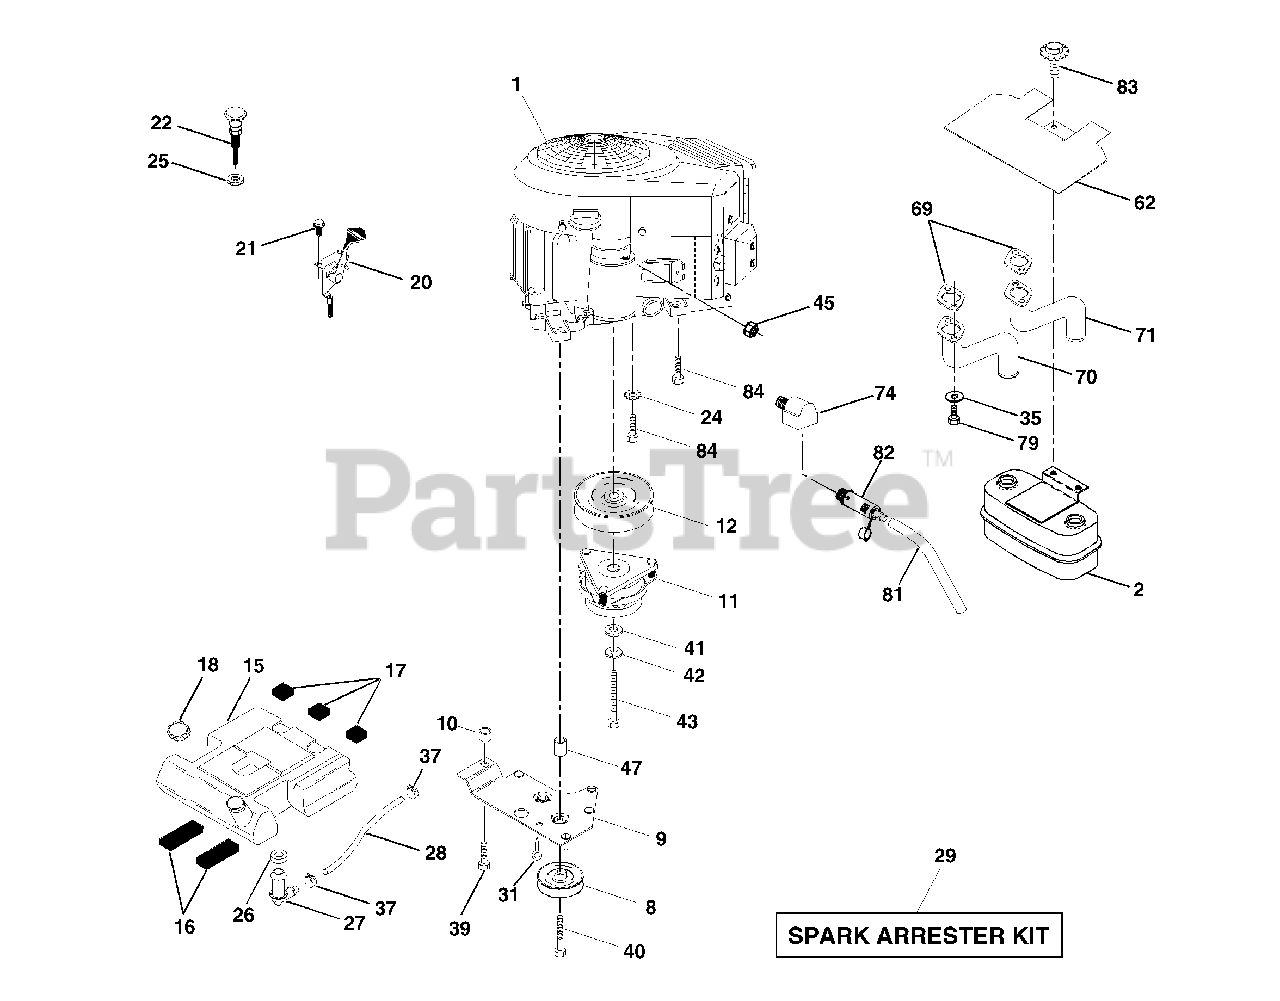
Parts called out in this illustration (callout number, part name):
2	Muffler Side
8	Pulley V-Idler
9	Keeper Asm. Belt Engine VGT
11	Clutch Electric
12	Pulley Engine VGT Elect Clutch
15	Tank Fuel Rear 3.50
16	Pad Spacer
17	Pad Spacer
20	Control Throttle
21	Screw Hex Thd Cut 1/4 - 20 X 5/8
22	Control Choke
24	Washer Ext Tooth 3/8
25	Nut Keps 3/8-24 Unf
27	Stem Tank Fuel
28	Fuel Line
29	Spark Arrester Kit
35	Washer
37	Clamp Hose
39	Screw TT 3/8-16 x 2-1/4 UNC
40	Screw TT 3/8-16 x 4 UNC
41	Washer 1-1/2 OD X 15/32 ID X .250
42	Washer Lock 7/16
43	Bolt Hex 7/16-20 X 4-1/4 Ga 5
45	Nut Keps Hex 1/4-20
62	Shield Heat Muffler CV-Intek
70	Tube Exhaust LH
71	Tube Exhaust RH
74	Elbow Street Brass
79	Screw Hex Hd Cap 5/16-18 x 3/4
81	Tube Drain Oil Easy
82	Plug Oil Drain Easy
83	Bolt 5/16-18unc X 1-3/4 W/Sems
84	Screw Thdrol 3/8-16 x 1-1/2
